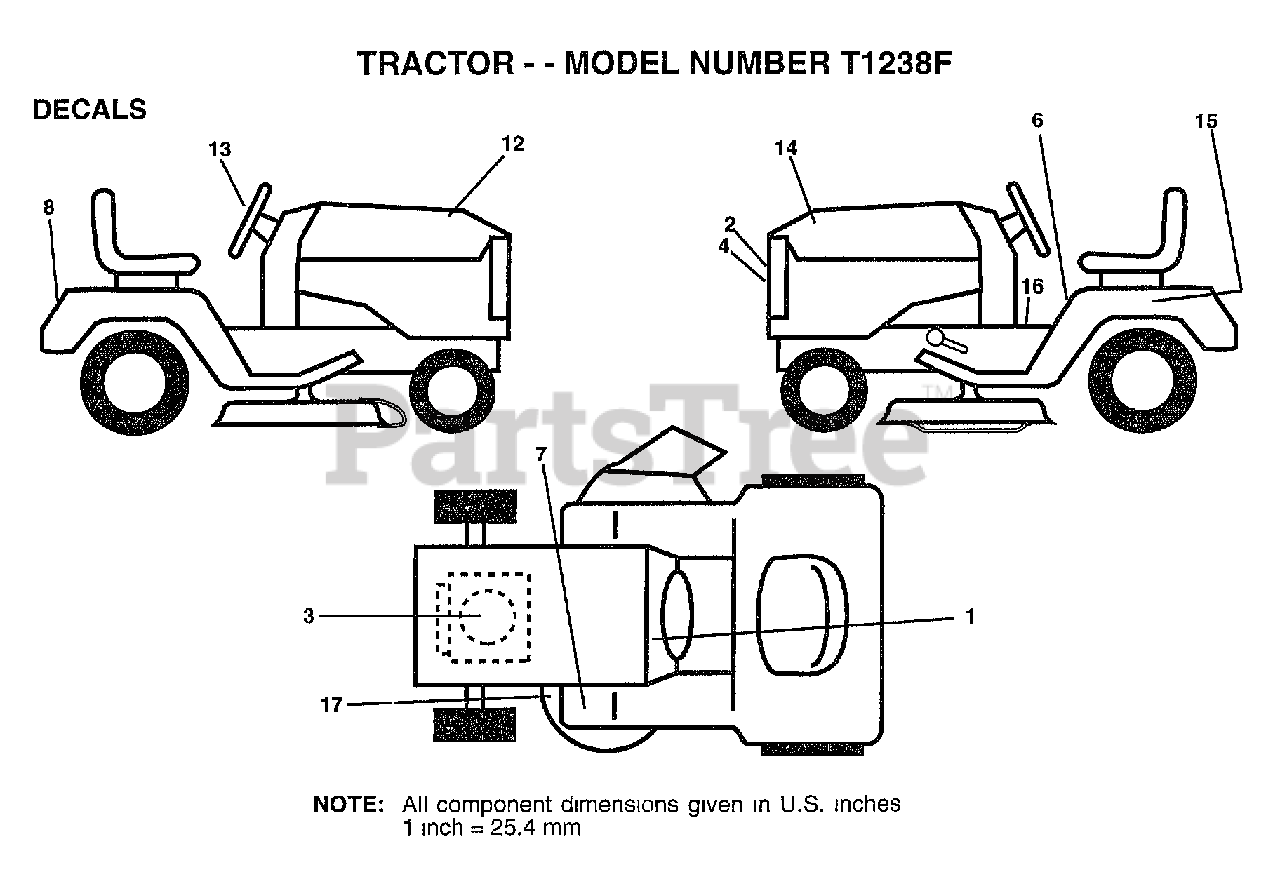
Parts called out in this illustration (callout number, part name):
1	"DECAL-OPER,GEAR D"
2	"DECAL,GRILL"
3	DECAL, HP ENGINE
4	DECAL.STRIPE.GR
6	"DECAL DANGER,FEND"
8	DECAL LOGO FENDER
12	DECAL HOOD RH
13	DECAL, STEERING WHEEL
14	DECAL HOOD LH
15	DECAL.BATRY.3-3908
16	DECAL BRAK PARK
17	DECAL
